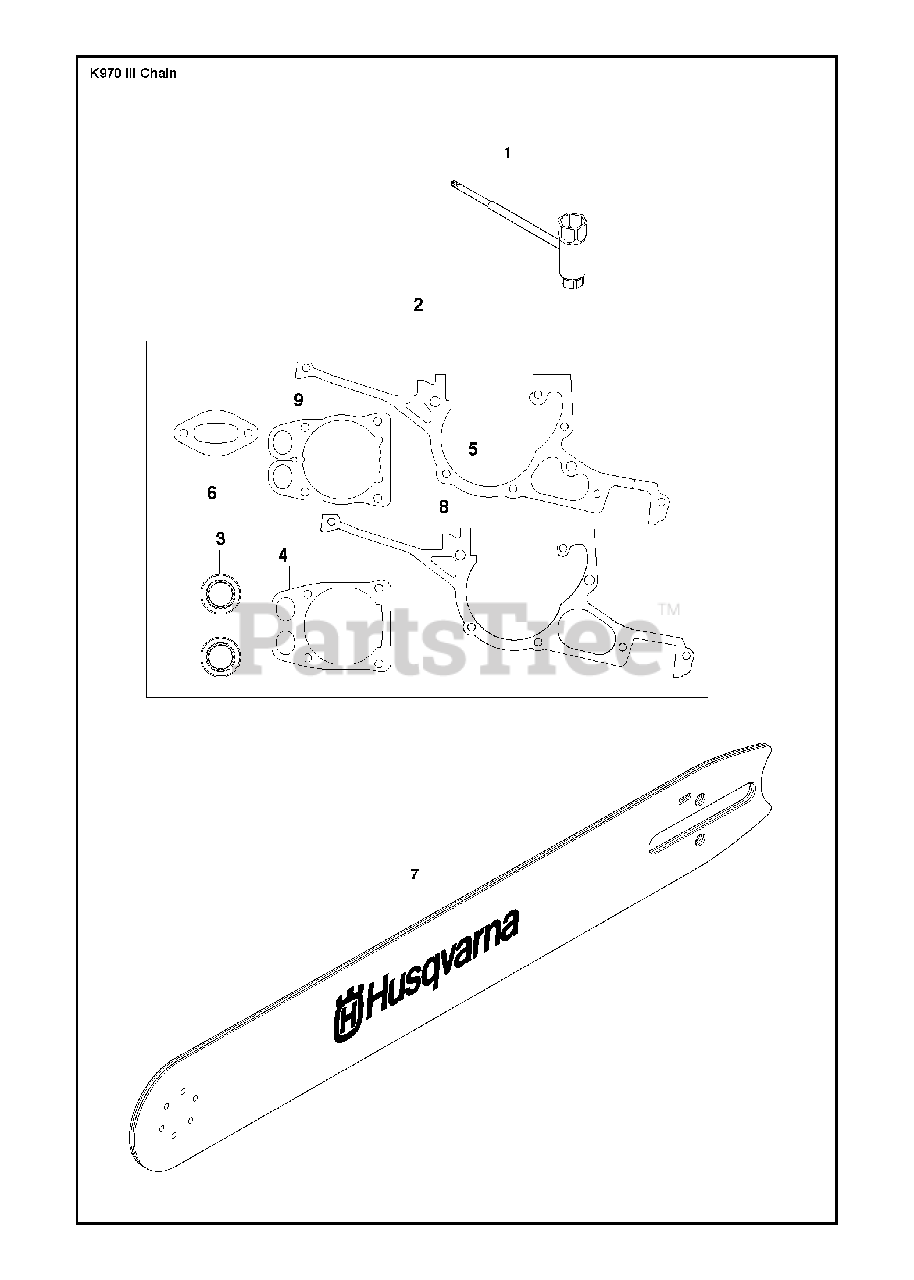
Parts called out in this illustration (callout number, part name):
2	GASKET KITIncl. 3-6, 8-9
3	SEALING RING
6	GASKET
7	BARFor 14" and 3/8" only
7	GUIDE BARFor 12" and .444" only
7	GUIDE BARFor 16" and .444" only
